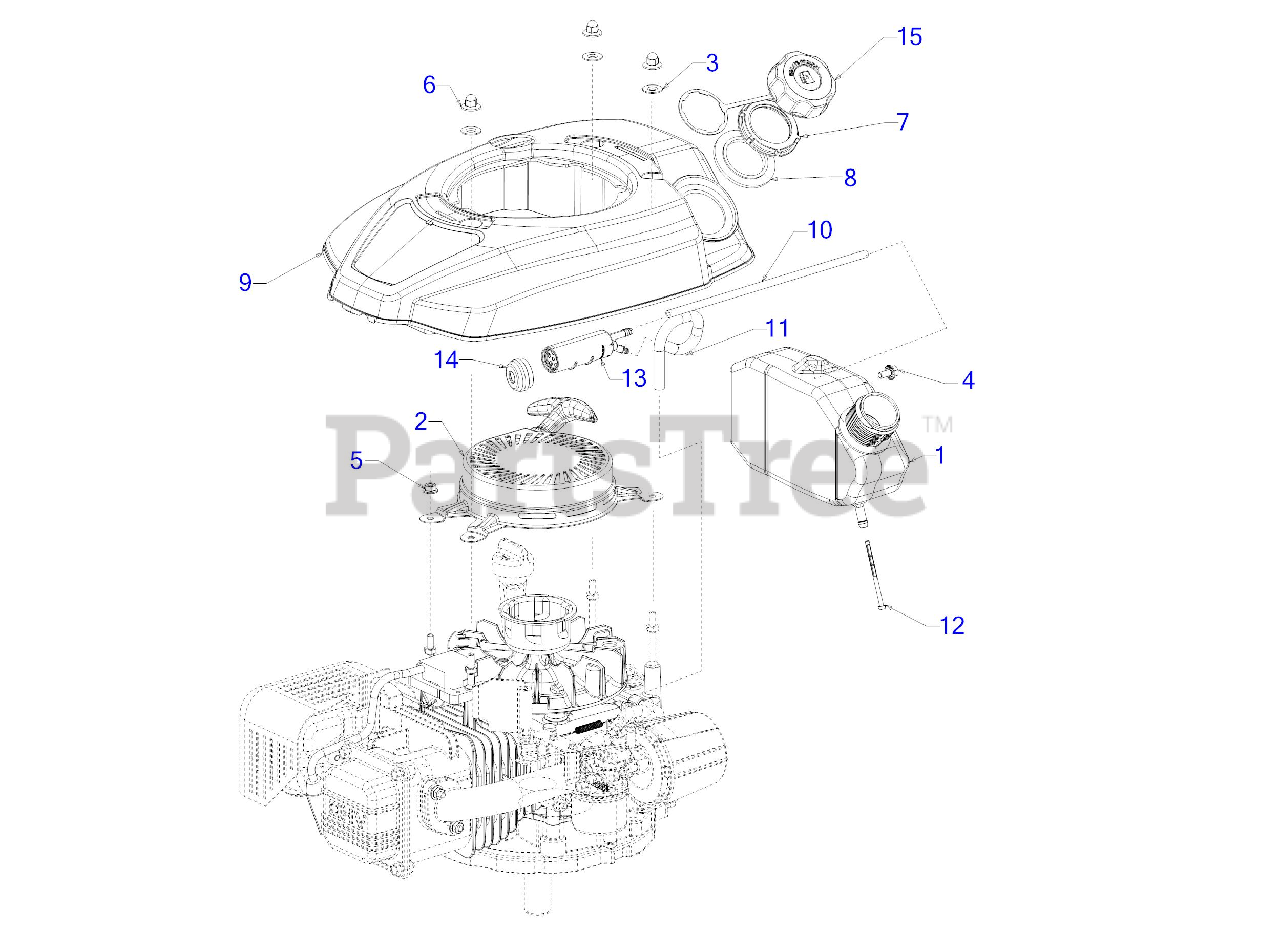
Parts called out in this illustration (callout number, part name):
1	FUEL TANK
2	STARTER PULLEY ASSEMBLY
3	SHROUD SPACER
4	SCREW M6-1 x 12 CL8.8
5	HEX FLANGE NUT
6	ACORN NUT
7	FUEL TANK NUT
8	FUEL TANK LOWER GROMMET
9	ENGINE SHROUD
10	HOSE-5 ID x 8 OD
11	HOSE-5MM
12	FUEL FILTER
13	CARBON CANISTER
14	CARBON CANISTER
15	FUEL CAP ASSEMBLY
